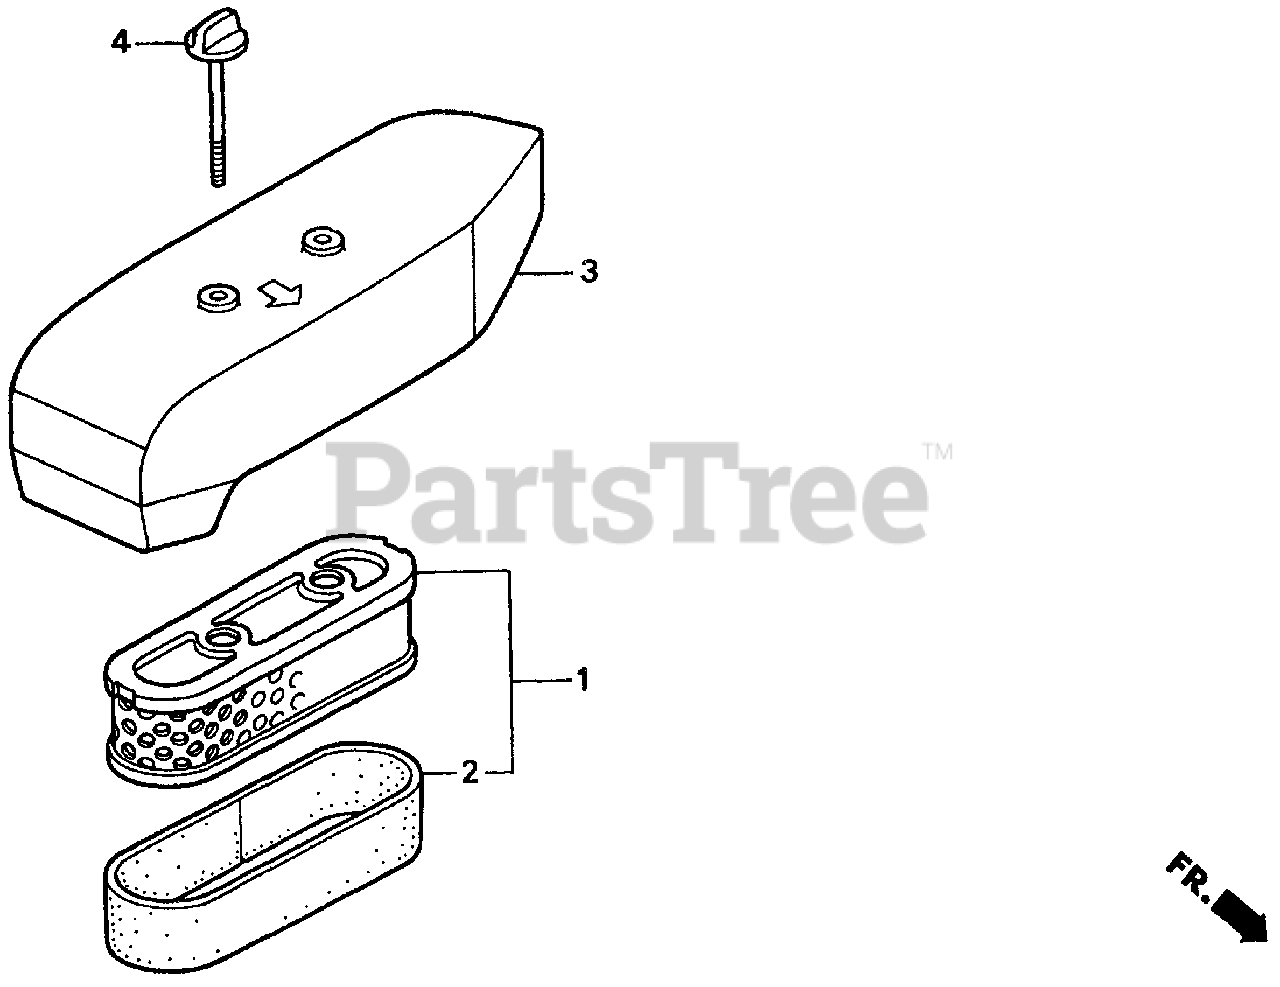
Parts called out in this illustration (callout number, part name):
1	ELEMENT, AIR CLEANER (TOUYOU)
2	FILTER (OUTER)
3	COVER, AIR CLEANER *NH1* (BLACK)
4	BOLT, AIR CLEANER (6X73)
5	GASKET, ELEMENT
6	GROMMET, AIR CLEANER
